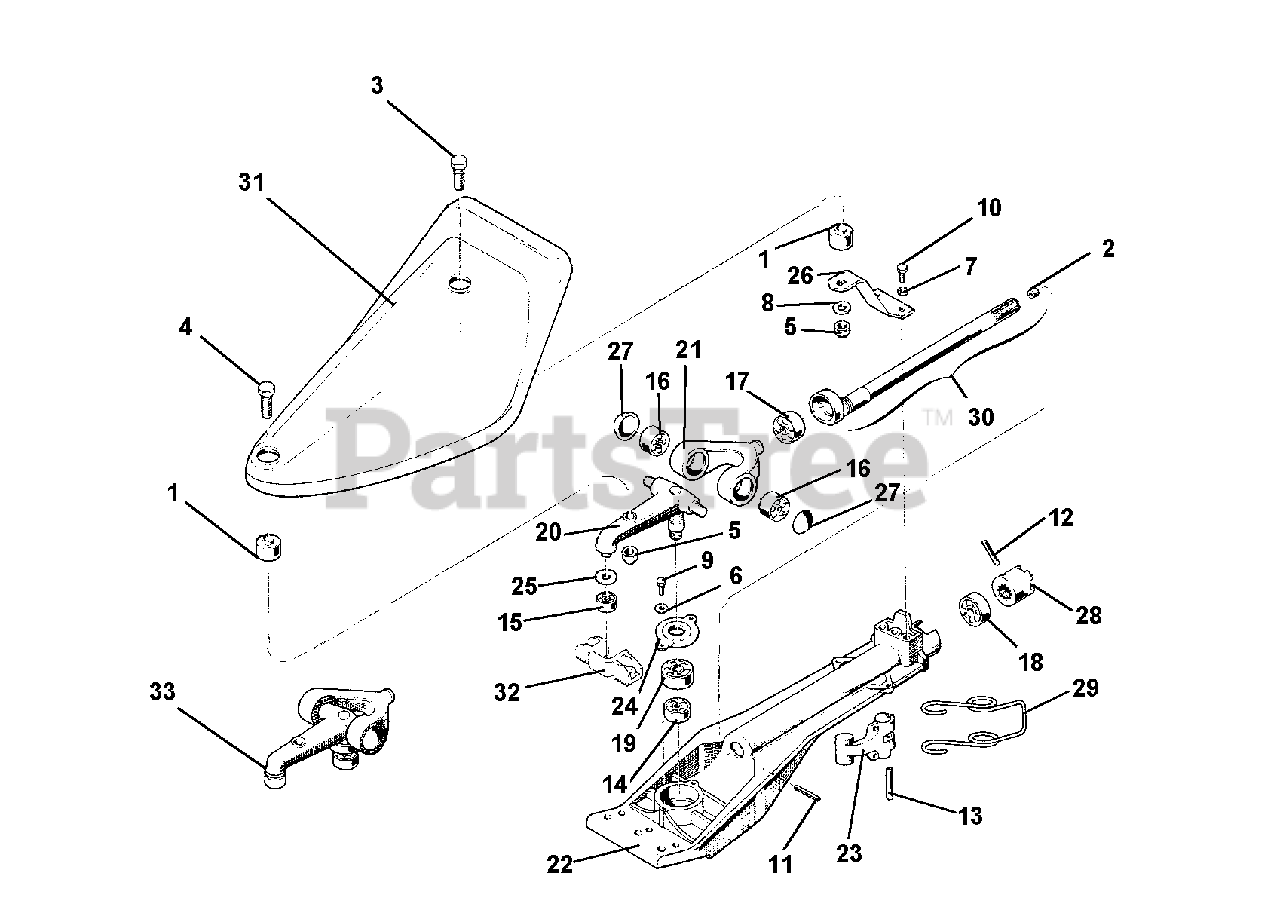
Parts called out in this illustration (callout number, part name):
3	SCREW M10 X 45
4	SCREW M10 X 60
5	NUT, SELF LOCKING M10
6	WASHER, LOCK 6.4
7	WASHER, LOCK 8.4
8	WASHER, LOCK 10.5
9	SCREW M6 X 12
10	SCREW M8 X 15
11	PIN, LOCKING 5 X 40
12	PIN, LOCKING 6 X 40
13	SPIRAL PIN 8 X 40
14	BEARING 12 X 37 X 12 6301
15	BEARING 62200-2RS 10 X 30 X 14
16	BEARING 15 X 35 X 11 6202 2RS
17	BEARING SKF 17 X 40 X 12 6203 ST
18	BEARING 20 X 42 X 12 6004 2RS
19	BEARING 20 X 47 X 14 6204-Z
20	BLADE CONTROL CRANK
22	CUTTER BAR SUPPORT
24	BEARING COVER
25	PROTECTION WASHER
26	ELASTIC CONNECTION
27	CLOSING DISC
28	PTO COUPLING
30	SHAFT WITH BUSHING
32	NYLON COUPLING
33	CRANK COMPLETE
